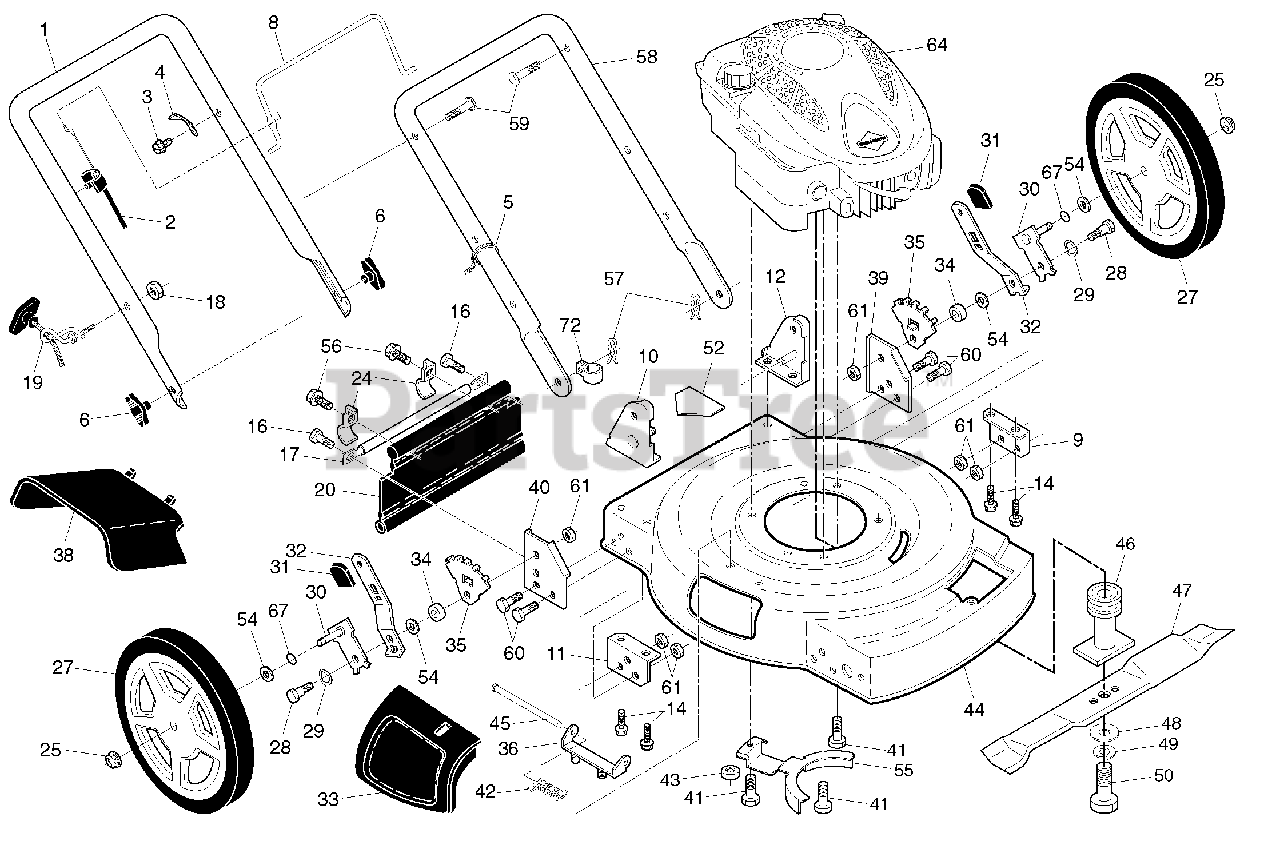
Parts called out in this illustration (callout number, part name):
1	Upper Handle
2	Engine Zone Control Cable
3	Screw
4	Bracket, Upstop
5	Wire Tie
6	Handle Knob
8	Control Bar
9	Support Bracket, Handle, LH
10	Handle Bracket, RH
11	Support Bracket, Handle, RH
12	Handle Bracket, LH
14	Screw, Thread Cutting 5/16-18 x 3/4
16	Screw
17	Support Rod
18	Locknut, Keps
19	Rope Guide
20	Rear Skirt
24	Clamp, Rear Skirt
25	Locknut, Hex 3/18-16
27	Wheel & Tire Assembly
28	Shoulder Bolt
29	Washer, Curved, Cylindrical
30	Axle Arm Assembly
31	Knob, Selector
32	Spring, Selector
33	Mulcher Door
34	Spacer
35	Bracket, Wheel Adjuster
36	Bracket, Housing
38	Deflector, Discharge
39	Support Bracket, LH
40	Support Bracket, RH
41	Screw, Hex Head, Threaded, Rolled 3/8-16 x 1-1/8
42	Spring, Torsion
43	Locknut, Hex
44	Kit, Lawn Mower Housing
45	Rod, Hinge
46	Blade Adapter / Pulley
47	Blade, 22"
48	Washer, Hardened
49	Washer, Lock, Helical
50	Screw, Hex Head, Grade 8 3/8-24 x 1-3/8
52	Decal, Danger
54	Washer, Flat
55	Belt Keeper
56	Screw, Hex Washer Head #10-24 x 1/2
57	Hairpin Cotter
58	Lower Handle
59	Handle Bolt
60	Bolt
61	Locknut
67	O-Ring
72	Clip, Cable
72	Operator's Manual, English
72	Operator's Manual, French
72	Repair Parts Manual
